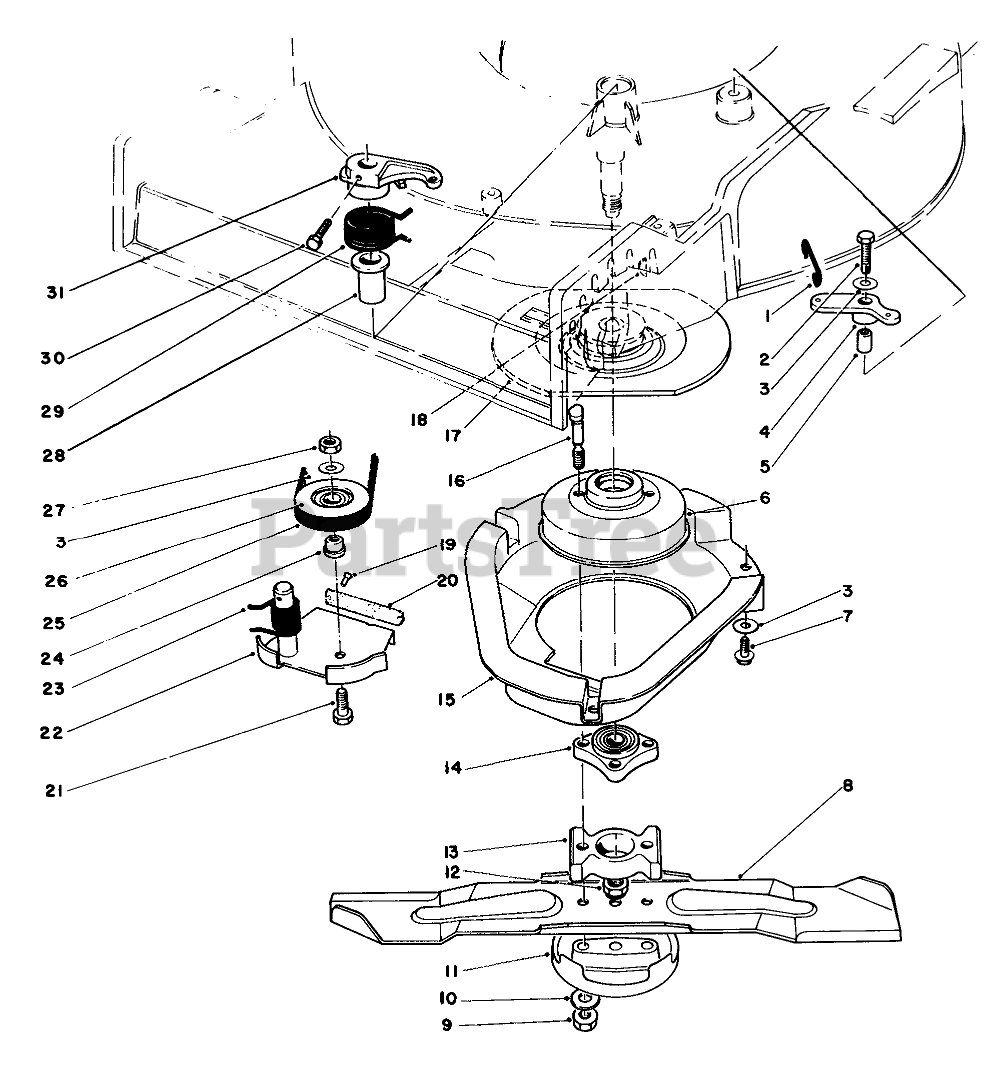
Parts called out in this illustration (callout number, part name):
1	LINK-CONTROL
2	SCREW-HH
3	WASHER-PLAIN
4	BELLCRANK
5	SLEEVE-BELLCRANK
6	Brake Drum
7	SCREW-HWHTF
8	BLADE-21in
9	NUT-LOCK
10	WASHER
11	Anti Scalp Cup
12	NUT-LOCK, NI
13	Spacer Blade
14	HUB ASM
15	SHIELD BBC
16	BOLT-BLADE
17	Flywheel
18	KEY-WOODRUFF
19	.185 DIA X .375 RT +
20	Paid
21	SCREW-HH
22	Brake Plate (Incl. Ref. #19 & 20)
23	SPRING-TORSION
24	HUB-PULLEY, IDLER
25	V-BELT
26	PULLEY-IDLER
27	NUT-LOCK, NI
28	BUSHING PM
29	SPRING-TORSION
30	SCREW-HH
31	LEVER
